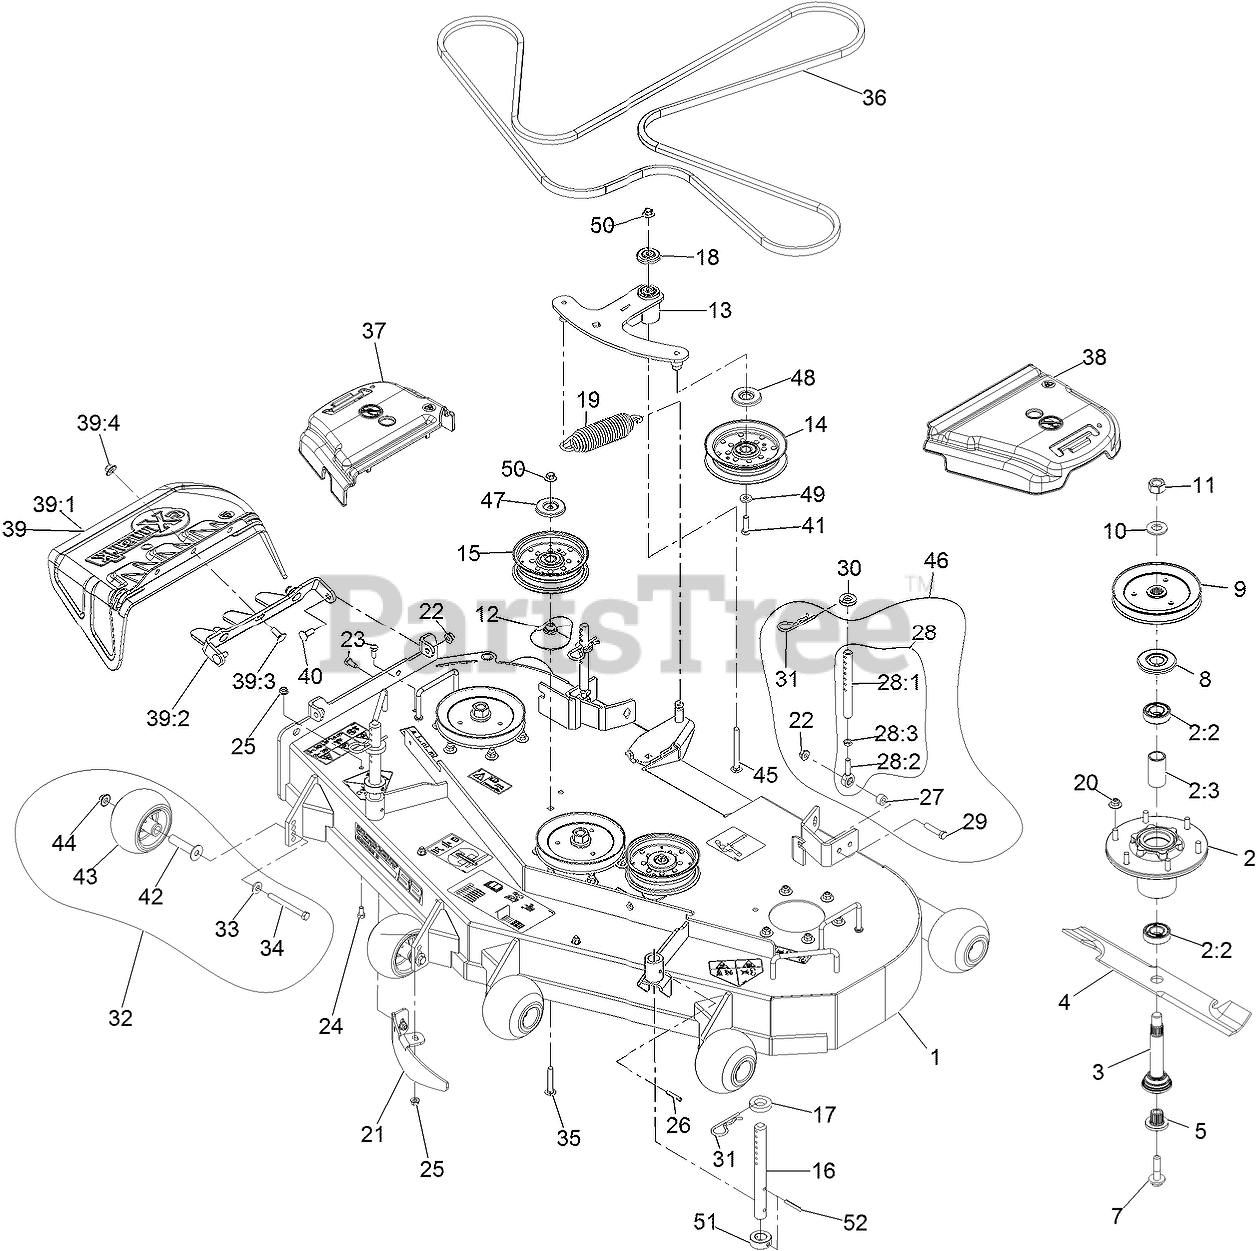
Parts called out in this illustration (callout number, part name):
1	ASM, DECK W/ DECALS, 52
2	ASM-CUTTER HSG WITH BEARINGS
2:2	BEARING-BALL
2:3	SPACER-BEARING
3	ASM-SPINDLE AND SEAL
5	BUSHING,SPLINED
7	SCREW,SEMS 1/2-20 X 2.19
8	GUARD,BEARING TOP .989
9	SHEAVE,BLADE DRIVE 6.50
11	NUT-HEX
12	SPACER-PULLEY
13	ASM, DECK IDLER
14	IDLER-PULLEY, FLAT
15	IDLER-PULLEY, FLAT 5.00X1
16	ROD, DECK SUPPORT TTS
17	SPACER-DECK SUPPORT
18	GUARD-TOP
19	SPRING-EXTENSION
20	Nut-Nyloc 3/8-16 Flg
21	BAFFLE, DOGLEG
22	NUT-HF, NI
23	SCREW-HH
24	SCREW-HH
25	NUT-HF, NI
28:1	LINK,SUPPORT
28:2	BALLJOINT
28:3	NUT-HJ
29	SCREW-HH
31	PIN,HAIR COTTER
32	KIT, ANTI-SCALP ROLLER
33	WASHER-BELLEVILLE
34	SCREW-HH 3/8-16 X 3 3/4 GR 8
35	BOLT-CARR, SHORT NECK
36	BELT, DECK
37	COVER-BELT, RH
38	COVER-BELT, LH
39	ASM, DISCHARGE CHUTE
39:1	CHUTE,DISCHARGE
39:2	BRACKET, DISCHARGE CHUTE
39:3	SCREW-CARR
39:4	Nut-Nyloc 3/8-16 Flg
40	SCREW-CARR
41	SCREW-HH
42	AXLE, ROLLER
43	ROLLER-SCALP, ANTI
44	Nut-Nyloc 3/8-16 Flg
45	SCREW-CARR
46	KIT,SUPPORT LINK W/PIN
47	SHIELD-DUST
48	SHIELD-GUARD, DUST
51	COLLAR, DECK HEIGHT PIN
52	PIN-ROLL
